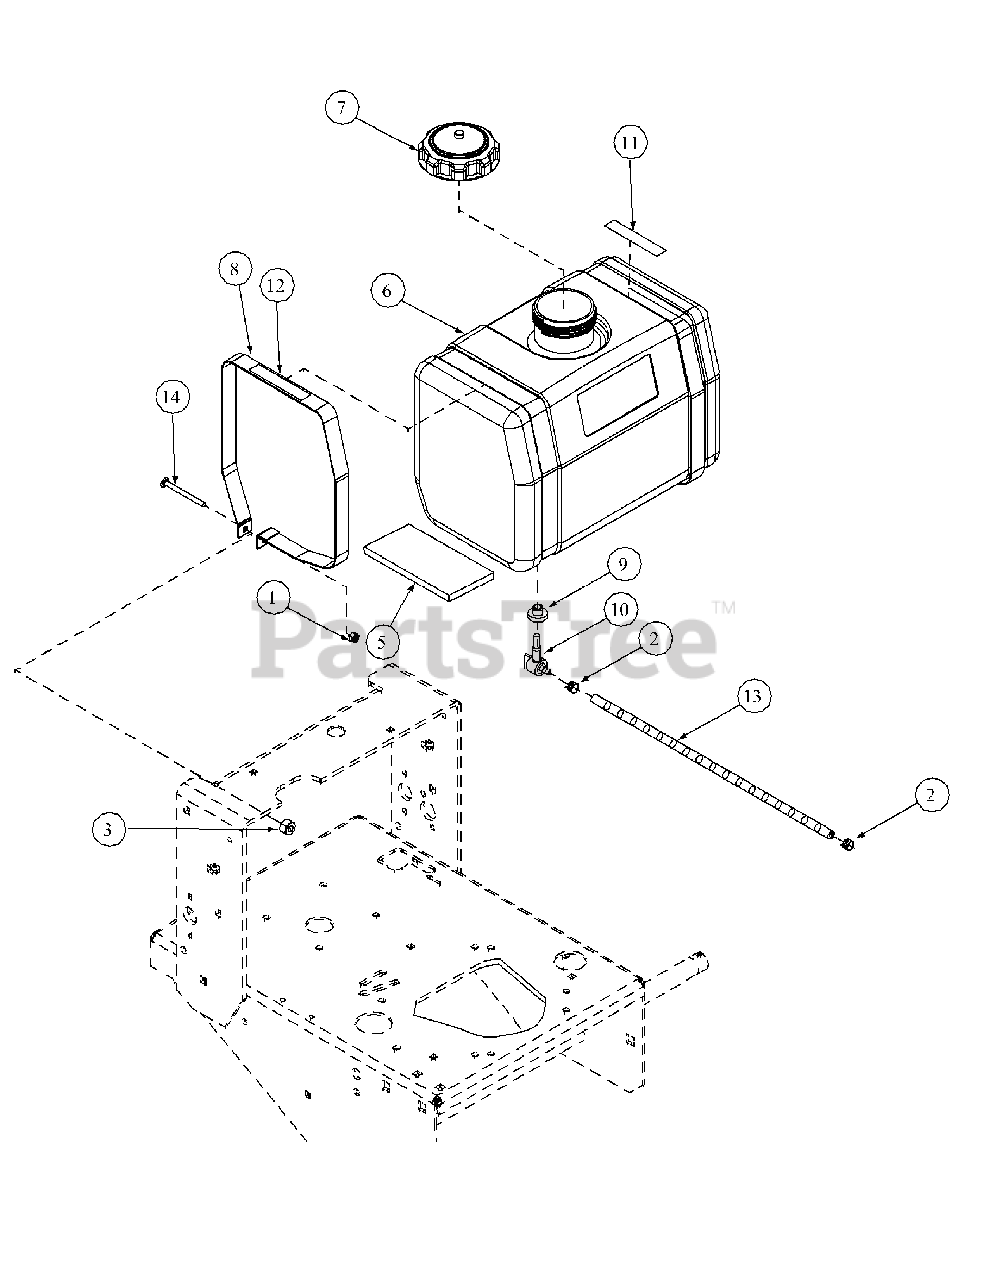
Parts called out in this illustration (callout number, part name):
1	Lock Nut, Nylon Insert, 1/4-20
2	Uni-Clamp
3	Spacer
5	Rubber Stop Pad
6	Fuel Tank
7	Fuel Cap, 3.5
8	Fuel Tank Strap
9	Grommet Fuel Tank
10	Shut Off Fuel Tank
11	Label, Mower Warning Turn Off Engine
12	Label, Mower Instruction, Fuel Valve
13	Hose Fuel, 18"
14	Carriage Bolt, 1/4-20 x 3.00
